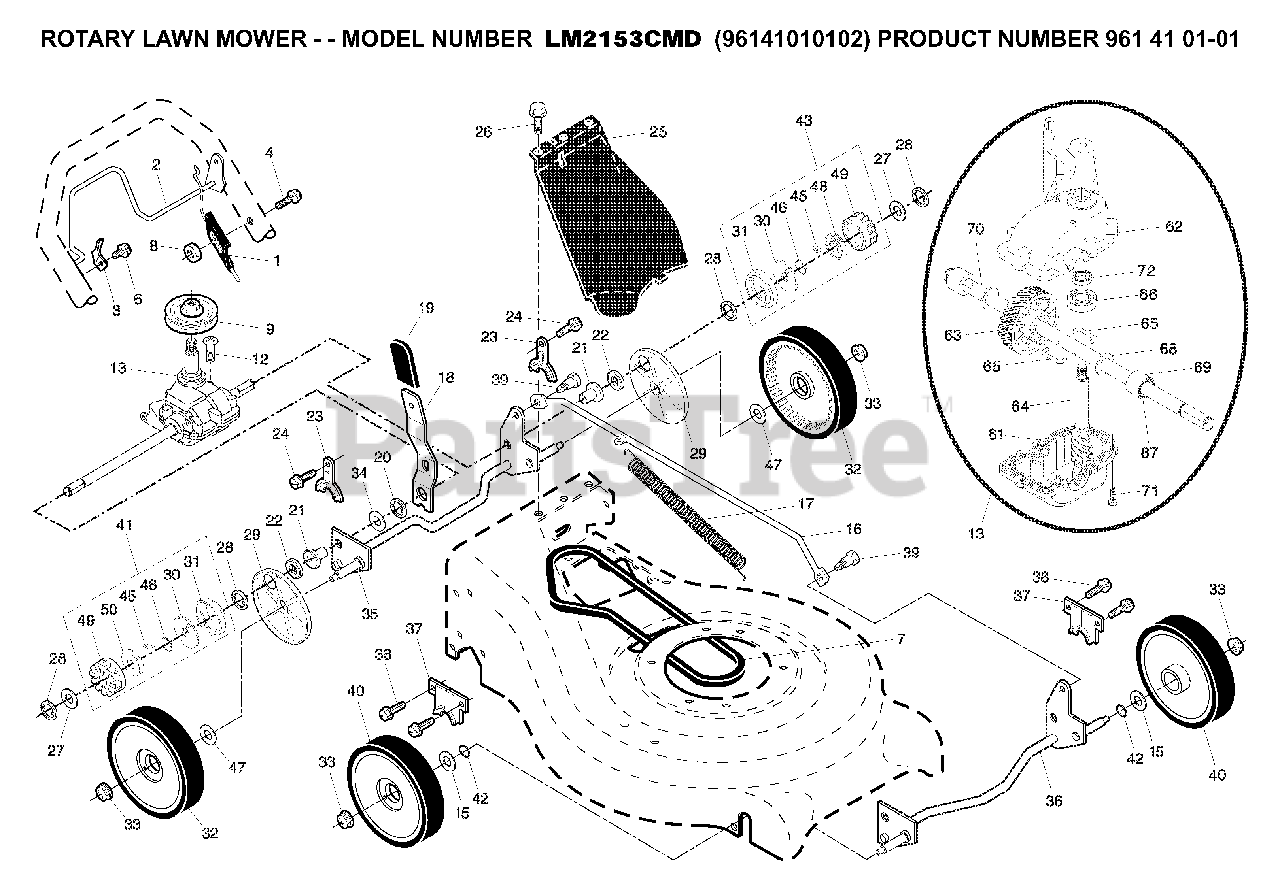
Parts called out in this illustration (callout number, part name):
2	BAIL.CONT.DR.21.RWGD.BLACK
3	DOWNSTOP BRACKET
7	V-BELT
8	NUT.HEX.FLANGE.1/4
13	TRANSMISSION.21.RWGD.AUTO.SP
15	WASHER PM
16	ROD.CONNECTING.SPT.BLACK
17	SPRING EXTENSION
18	SPRING.SELECTOR.SPT.21
19	KNOB, SELECTOR SPRING
21	RP BEARING SUPPORT
22	BEARING, BALL
23	BRACKET
27	WASHER
28	E-RING 7/16 RE
29	COVER.DUST.WHEEL
30	DISC.DRIVE.21.EZ-WALK
31	SEAL.PINION
33	NUT.HEX.FLANGE.3/8-16.LOCKNUT
35	SHAFT ASSY REAR
36	SHAFT ASSY, FRONT
37	RETAINER.FRONT.SHAFT
39	SHOULDER BOLT SEMI GIMLET PT.
41	PINION ASSY, RH
42	O-RING..070X.487.NEOPRENE
43	PINION ASSY, LH
45	PAWL.DRIVE.21.EZ-WALK
46	SPRING, TORSION
47	WASHER FLUT
48	RETAINER.DRIVE.21.EZ-WALK.LT
49	GEAR, PINION
50	RETAINER, DRIVE, RH
61	CASE, LOWER
62	CASE, UPPER
63	GEAR.24.TOOTH.WALK.MOWER
64	SHAFT INPUT
65	WIRE, FORMED
67	SEAL.OUTPUT.SHAFT
70	SHAFT.OUTPUT.RGD.VS/EZ
72	SEAL INPUT SHAFT
